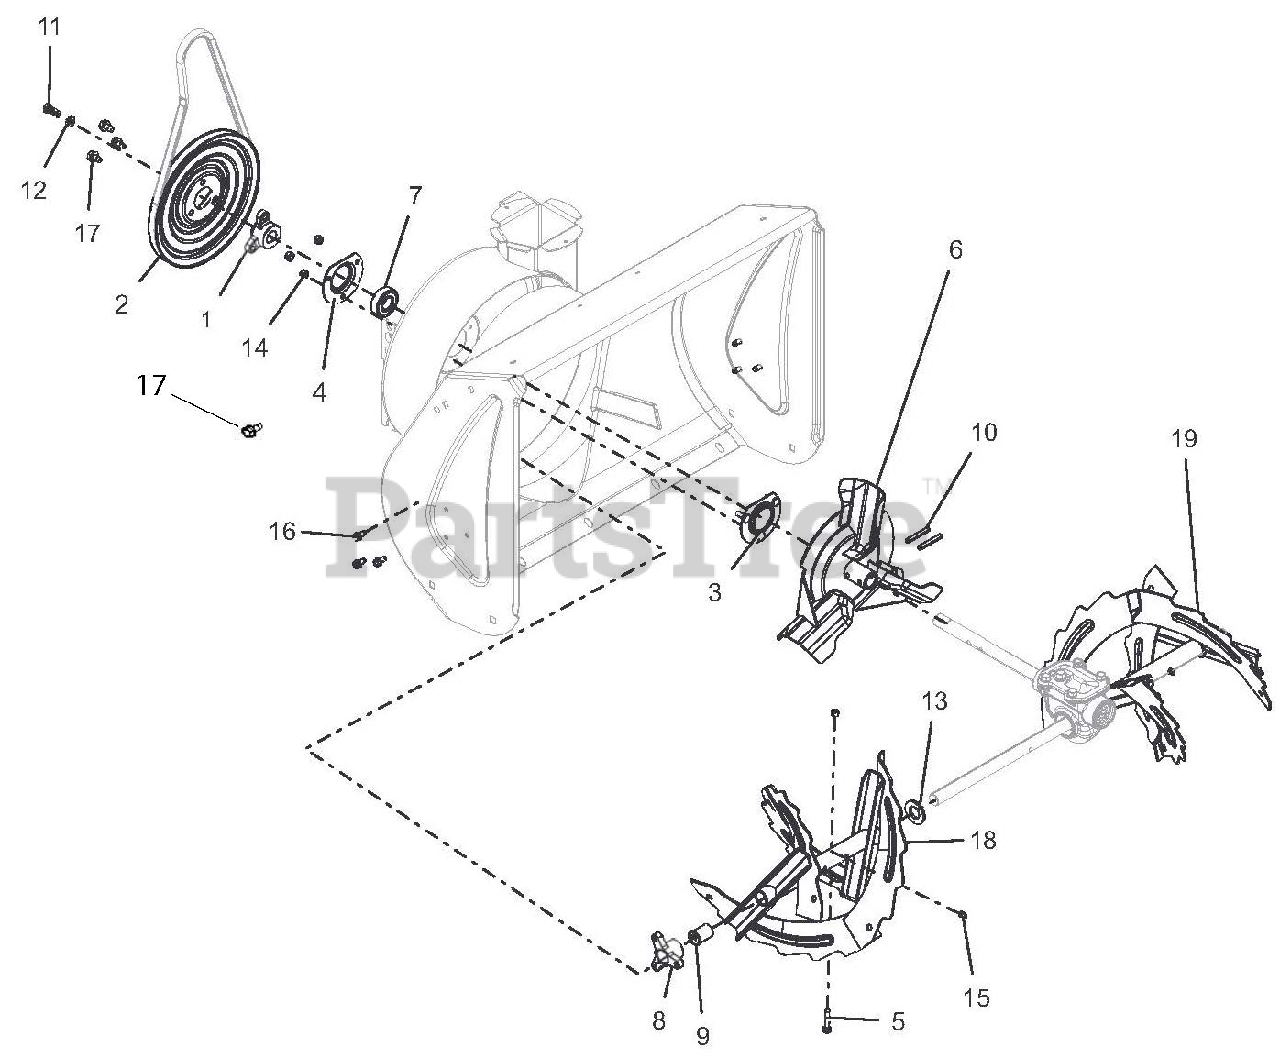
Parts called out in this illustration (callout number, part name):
1	PULLEY HUB, BOLT-ON D-BORE .75
2	PULLEY,SPIN FORM SINGLE GROOVE
3	BEARING FLANGE
4	BEARING FLANGE
5	SHEAR BOLT
6	IMPELLER, COMPACT 12" 3-BLADE
7	BRG-BALL .750X1.750X.50
8	BUSHING, RAKE SHAFT .75"
9	BSHG-FLG SPLIT NYLINER .75"ID
10	PIN-ROLL .250X1.75
11	BLT-HEX .31-24X.75 YWZC GR5
12	WSHR-LK .312X.097 HVY YWZC
13	@WSHR-FL-STL.812X1.50X.135YWZC
14	@NUT-LK-CTR .25-20 YWZC
15	ZERK,FITTING .25X.125 DRIVE IN
16	SCR-TAP .25-20X.50 HWH TR YWZ
17	@SCR-TAP .31-18X.50 HWH TR YWZ
18	RAKE, 24" RH, BLK SERR W/ZERK
19	RAKE, 24" LH, BLK SERR W/ZERK
